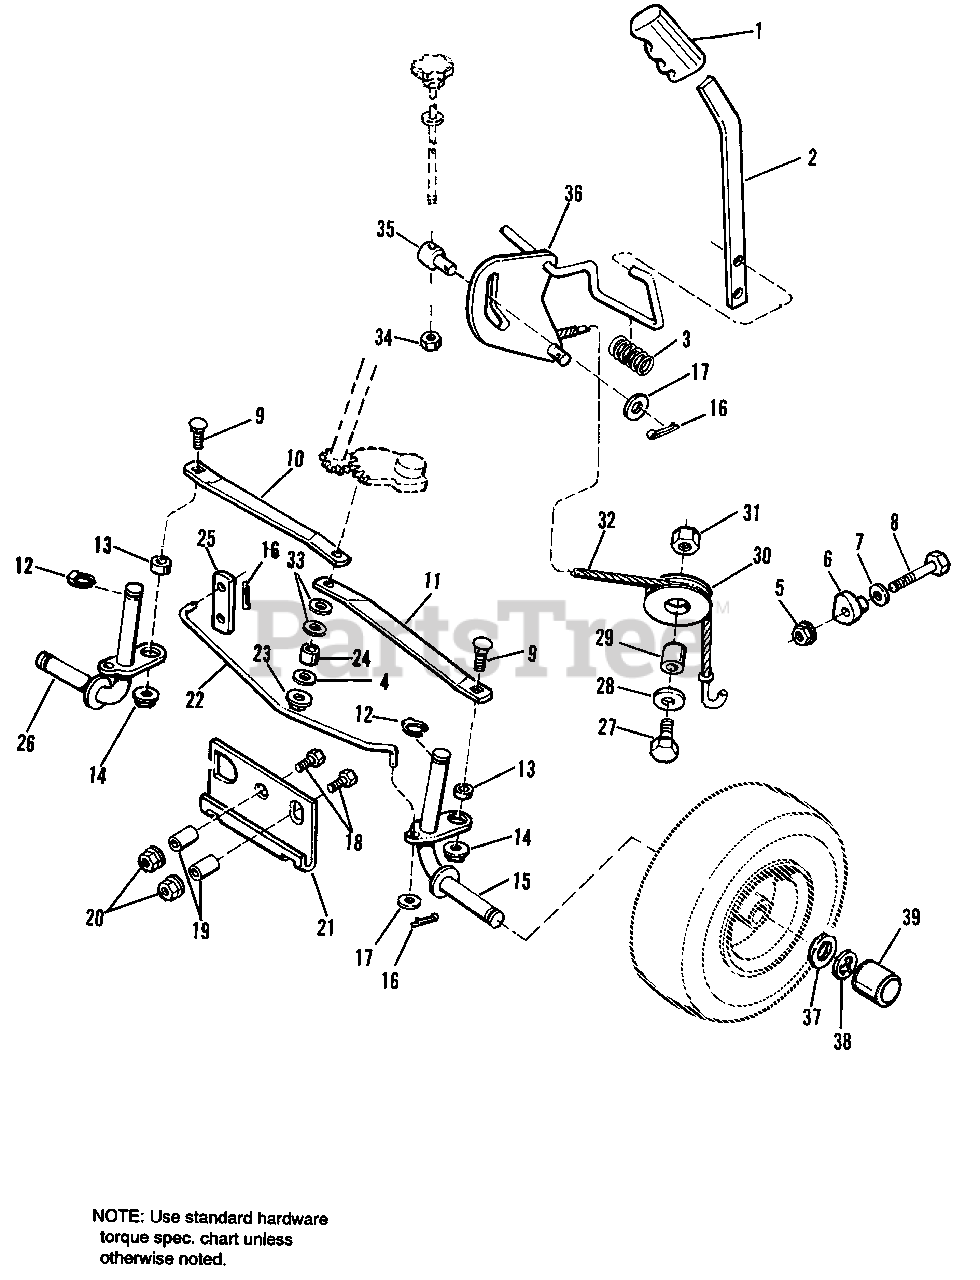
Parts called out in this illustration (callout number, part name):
1	GRIP, Lever
2	LEVER, Lift
3	SPRING, Compression
4	WASHER, Plain,11/32 x 1 x 1/8
5	NUT, Hex, Flange Lock, 3/8-16
7	WASHER, Plain,13/32 x 7/8 x 1/8
8	CAPSCREW, Hex Hd., 3/8-16 x 1-3/4
9	CARRIAGE BOLT, 3/8-16x 1
10	TIE ROD, R.H.
11	TIE ROD, L.H
14	NUT, Hex, Flange Lock, 3/8-16
15	SPINDLE ASSY., L.H.
16	COTTER PIN, 3/32 x 3/4
17	WASHER, Plain, 13/32 x 7/8 x 5/64
18	CAPSCREW, Hex Hd., 1/2-13 x 1-1/2
20	NUT, Hex, Flange Lock, 1/2-13
21	HITCH, Hook
23	NUT, Hex, Flange Lock, 5/16-18
24	SPACER, 21/64 x 1/2 x 5/8
26	SPINDLE ASSY., R.H.
27	CAPSCREW, Hex Hd., 3/8-16 x 1-1/2
28	WASHER, Plain, 13/32 x 1-1/2 x 1/8
30	PULLEY, Lift
31	NUT, Hex, Esna Lock, 3/8-16
32	CABLE ASSY., Lift
33	WASHER, Plain
34	NUT, Hex, 3/8-16
36	ARM ASSY., Lift
37	WASHER, 3/4
39	CAP, Threaded
